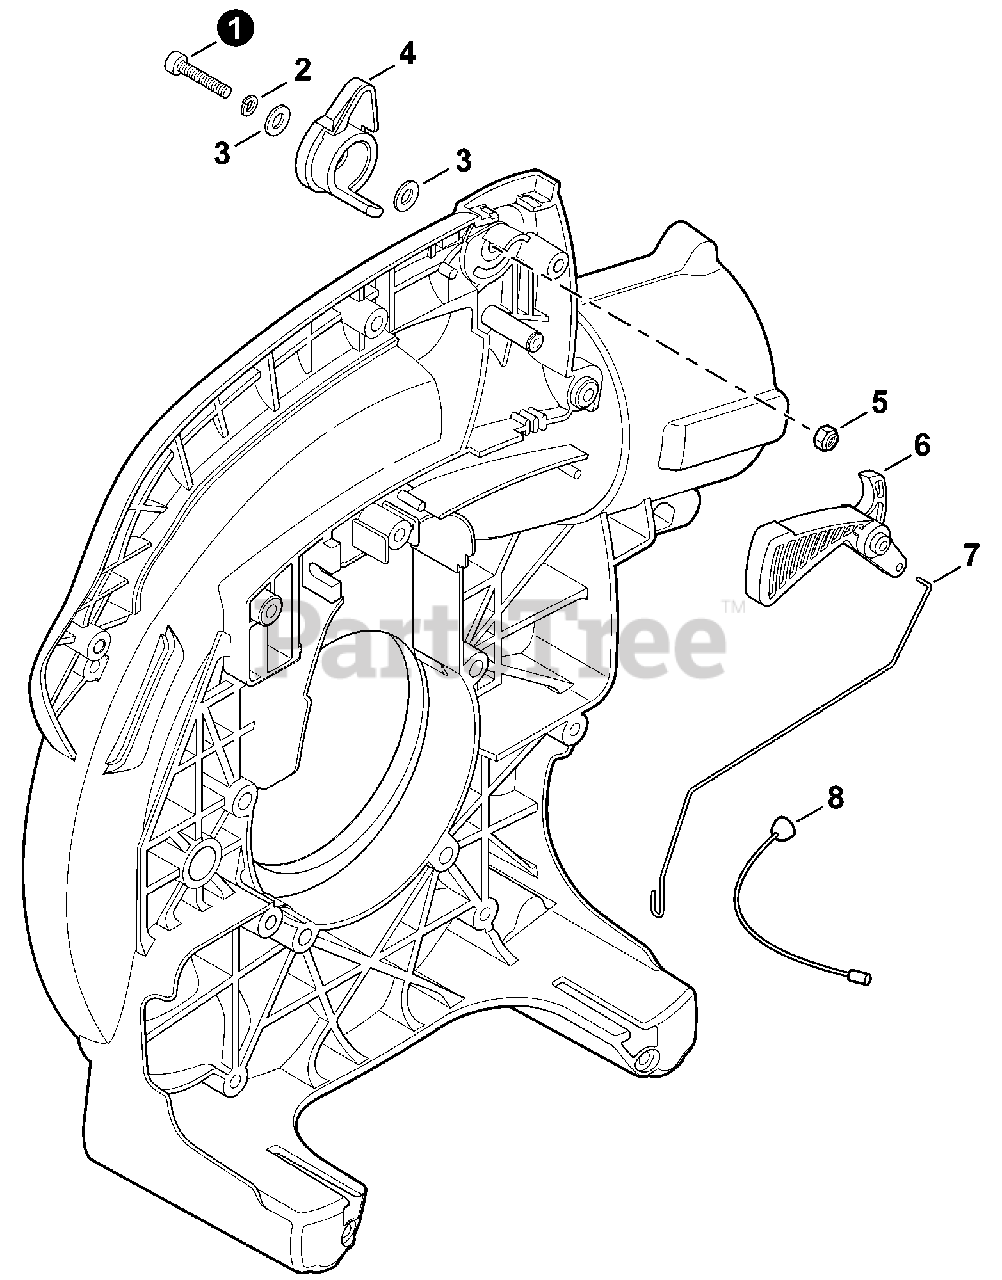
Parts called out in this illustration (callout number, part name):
1	BOLT, TORX 5×25
2	WASHER, SPRING 5
3	WASHER 5.5×12×0.8
4	CONTROL, THROTTLE
5	NUT, LOCK M5
6	TRIGGER, THROTTLE
7	ROD, THROTTLE
8	CABLE, THROTTLE
